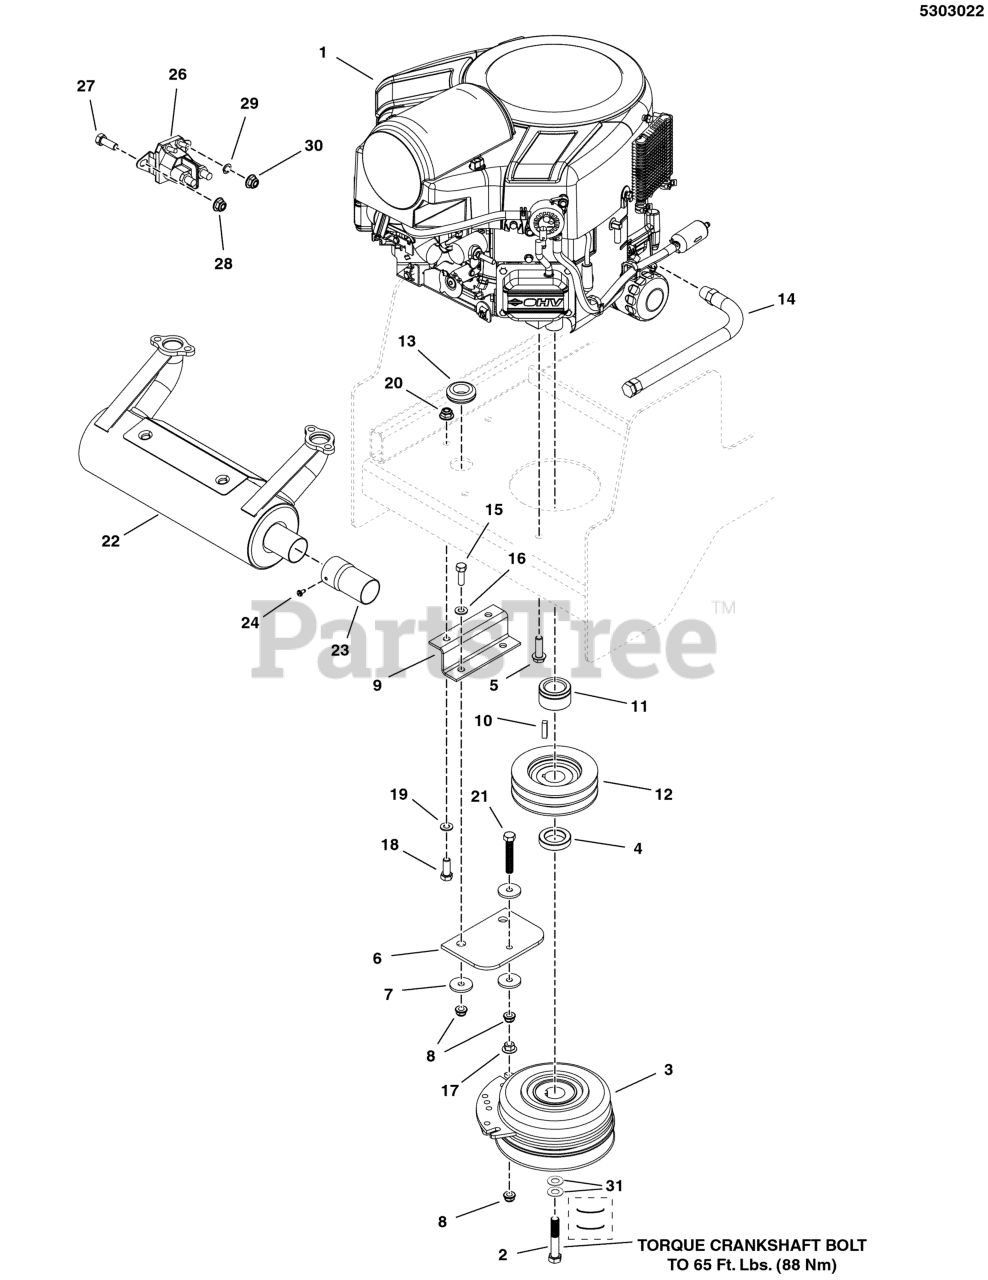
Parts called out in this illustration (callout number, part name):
1	ENGINE, 26HP, B&S, COMM TURF
2	BOLT, CRANKSHAFT,7/16-20X2-1/2, GD8
3	* CLUTCH, 5218-134, WARNER
4	SPACER, 1.13 X 1.75 X .50
5	BOLT, 5/16-18 X 1-3/4 GD5 YZ
6	CLUTCH ANCHOR PAD
7	WASHER, .34 X 1.25 X 10 GA
8	NUT, 5/16-18 HEX NYLOCK FLANGE
9	ANCHOR, CLUTCH - BLK
10	KEY, 1/4 SQ X 1
11	SPACER, 1.13 X 1.75 X 1.03, CZ
12	PULLEY, CRANKSHAFT, 1.126 ID X 4.75 OD
13	GROMMET, 7/8
14	HOSE, OIL DRAIN
15	BOLT, 5/16-18 X 1 GD5 YZ
16	WASHER, 5/16" SAE
17	NUT, 5/16-18 HEX SERRATED FLANGE (LARGE)
18	BOLT, 3/8-16 X 1" GD5 CZ
19	WASHER, 3/8 SAE
20	NUT, 3/8-16 HEX NYLOCK FLANGE
21	BOLT, 5/16-18 X 2-1/4 TFL, GD5 YZ
22	MUFFLER, B&S-ELS 22-26HP
22	MUFFLER, RIGHT OUTLET ASSY
23	EXTENSION, TAILPIPE, 3" - BLACK
24	SCREW,SELF-TAP,#8-32 X 3/8,WASH HEX, CZ
26	SOLENOID-4 POLE 12 VOLT DC (TROMBETTA)
27	BOLT, 1/4-20 X 3/4 GD5 YZ
28	NUT, 1/4-20 HEX SERR. FLANGE
29	WASHER, 5/16 LIGHT LOCK
30	NUT, 5/16-24 JAM
31	BELLEVILLE WASHER 1.1875 X .442 X .089
